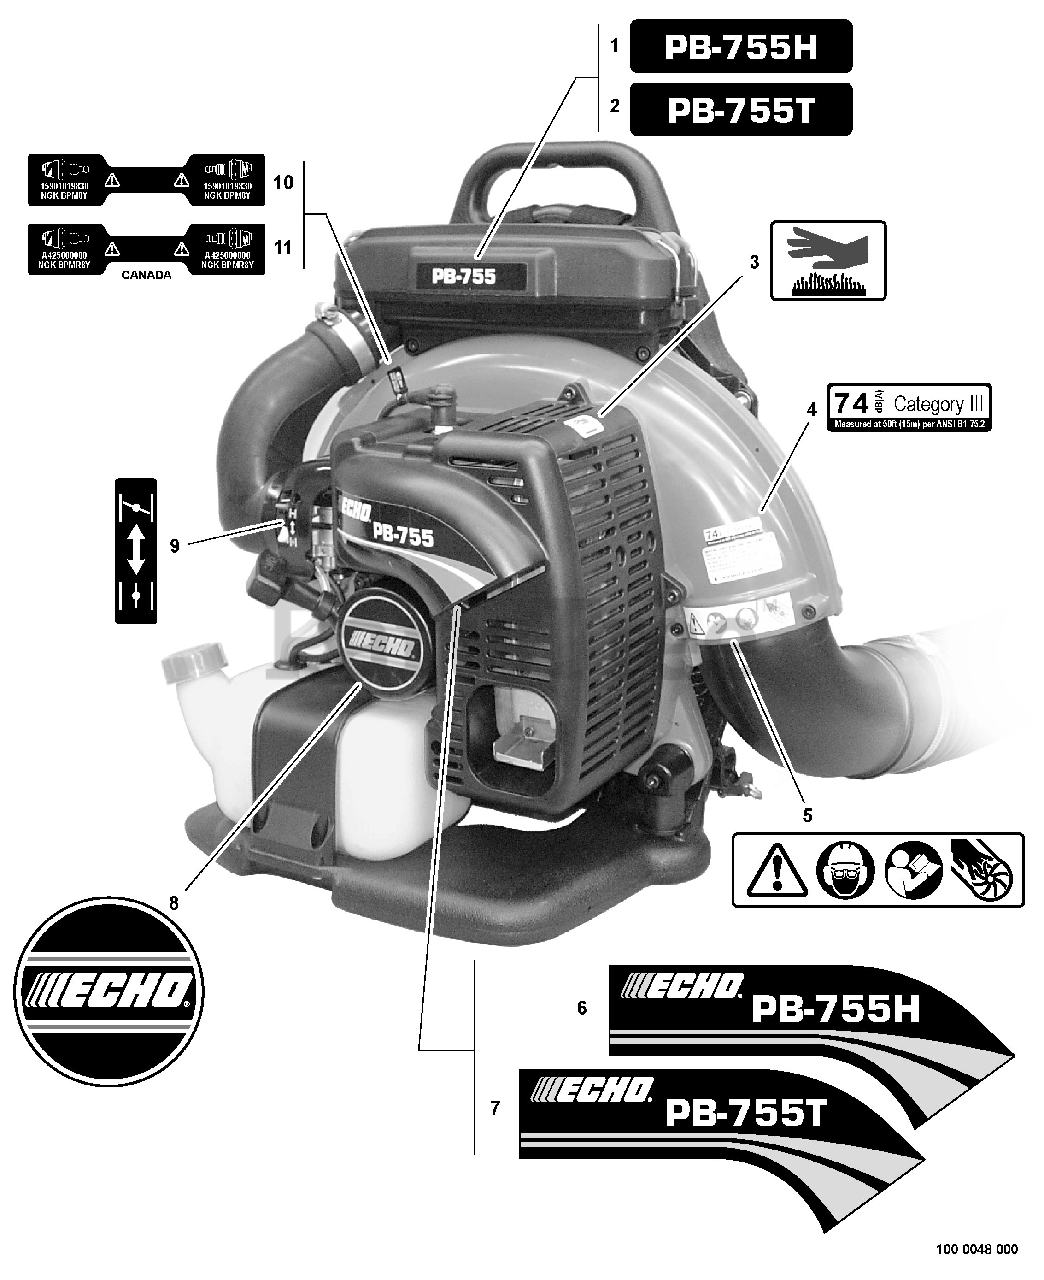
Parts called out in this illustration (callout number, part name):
1	LABEL - MODEL PB-755H
2	LABEL - MODEL PB-755T
3	LABEL - HOT SURFACE
4	LABEL - NOISE 74dB(A) CAT III
5	LABEL - CAUTION
6	LABEL - MODEL PB-755H
7	LABEL - MODEL PB-755T
8	LABEL - ECHO
9	LABEL - CHOKE
10	LABEL - SPARK PLUG -- BPM-8Y
11	LABEL - SPARK PLUG -- BPMR-8Y
